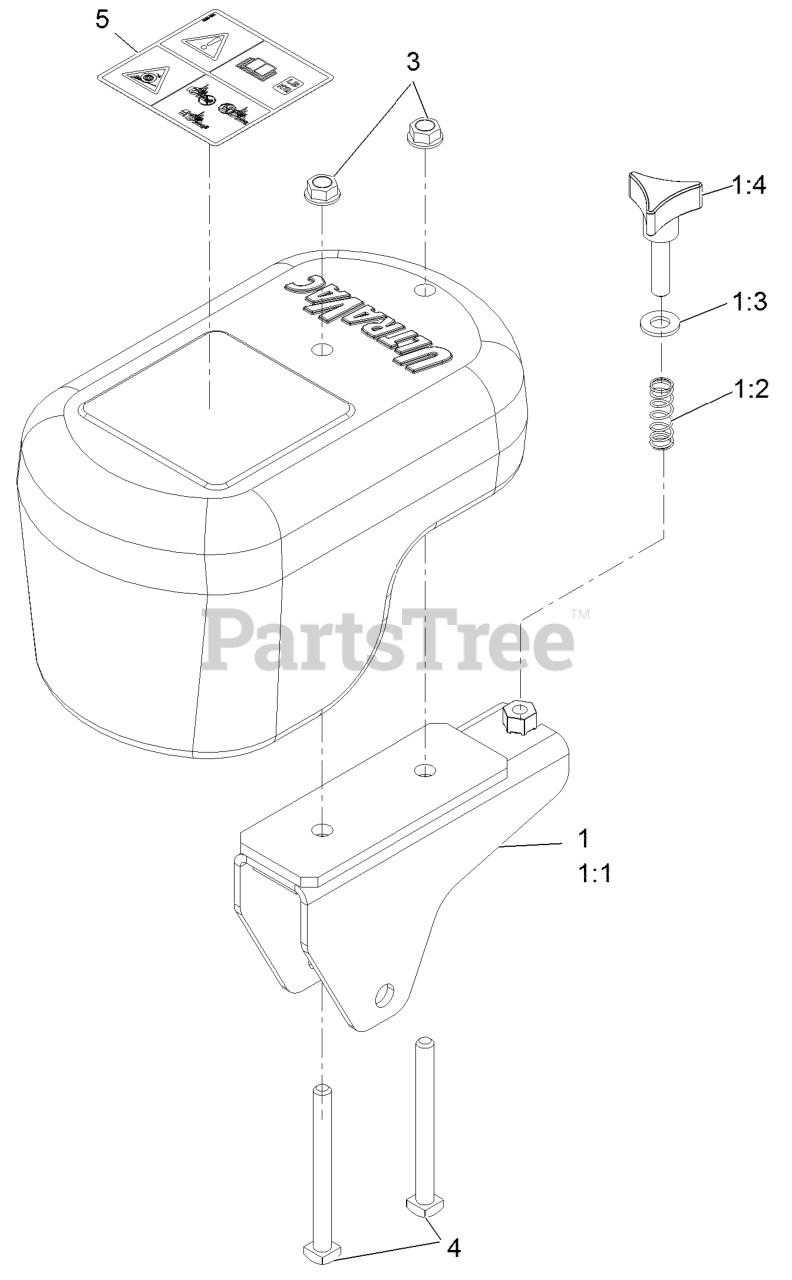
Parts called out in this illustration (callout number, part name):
1	ASM,Caster Weight Bracket
1:1	Wld,Caster Weight Bracket
1:3	Washer-3/8 SAE
3	Nut-Whizlock 3/8-16
4	Bolt-Square Hd 3/8-16 X 4
5	Decal-Warning, Traction
